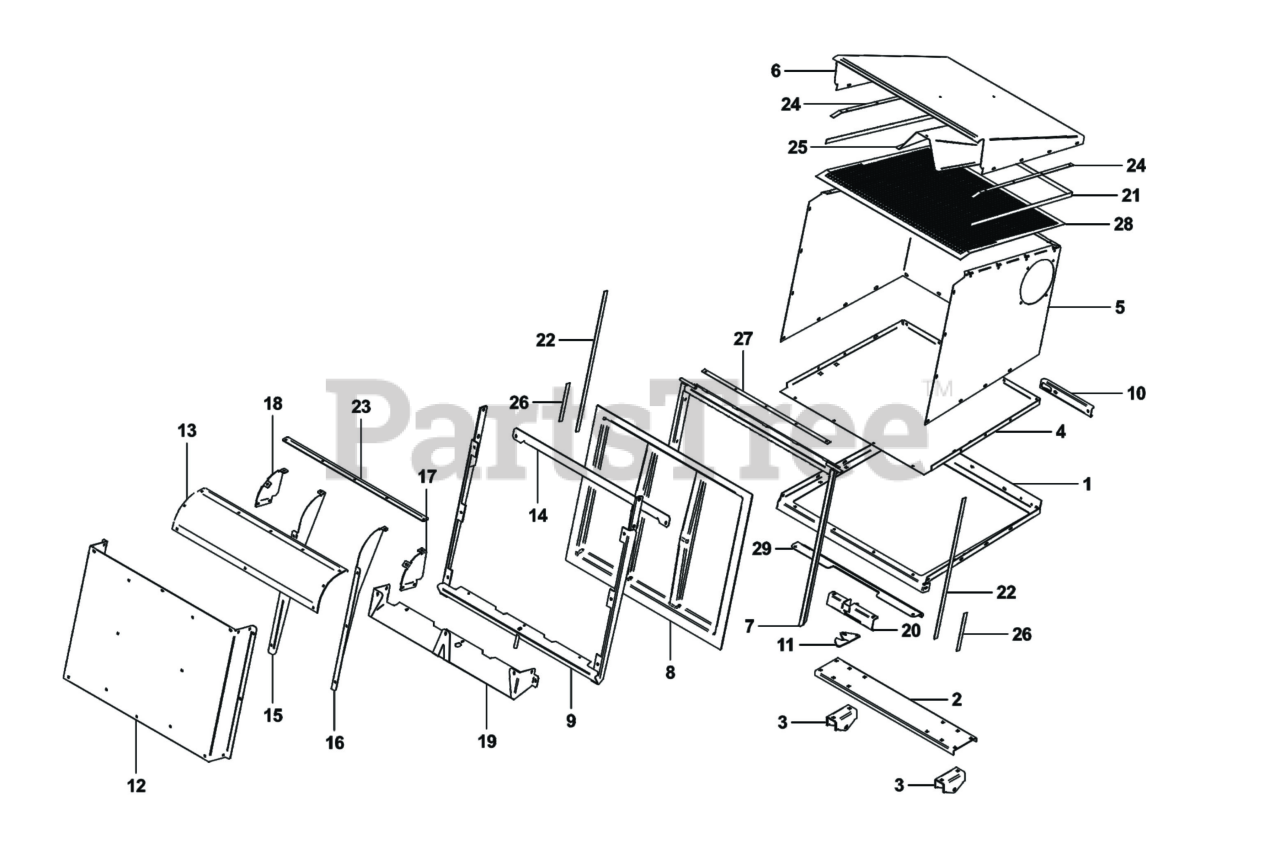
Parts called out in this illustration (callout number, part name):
1	FRAME-BASE
2	BASE FRAME PIVOT M
3	PIVOT BRACKET
4	ALUMINUM BOX BOTTO
5	BOX-BACK & SIDES
7	BOX/DOOR FRAME
8	PLASTIC DOOR
9	DOOR FRAME ASSEMBL
10	HANDLE MOUNT
11	LATCH HOOK
12	DUST DIVERTER
13	Dust Flap
14	UPPER DOOR MEMBER
15	BRACE-DUST DVRTR (LH)
16	BRACE-DUST DVRTR (RH)
17	BRACE-DUST FLAP RH OUTER
18	BRACE-DUST FLAP LH OUTER
19	BRKT-DUST DIVERTER GUARD
20	LATCH MOUNT PLATE ASSY
21	Dust Seal/Top Sides
22	Dust Seal/Long Door Sides
23	STIFFENER-DUST FLAP
24	SCREEN CLAMP STRIP-SIDE
25	SCREEN SUPPORT
26	Dust Seal/Short Door Sides
27	SCREEN CLAMP STRIP-REAR DOOR
29	STOP-BOX 6512
